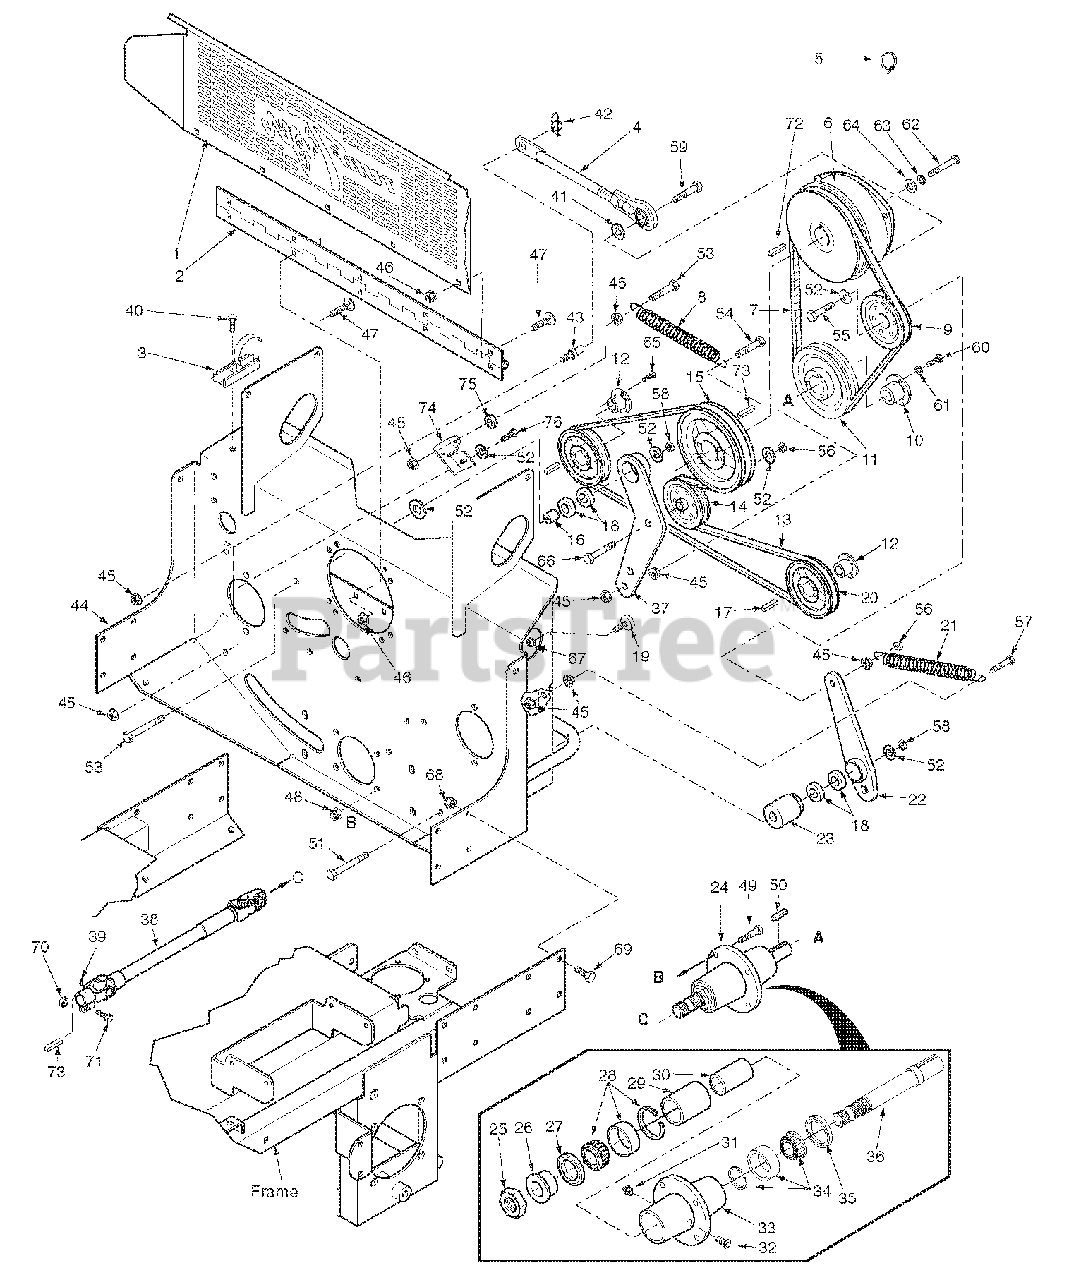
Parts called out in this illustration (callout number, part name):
1	Belt Guard, Rear
2	Hinge, Belt Guard
3	Latch, Hood
4	Rod Assembly, Clutch Anti-Rotation
5	Clamp, Cable
6	Clutch, Ogura GT-3.5
7	Belt, Deck Drive
8	Spring, Transmission Idler
9	Pulley, Idler 5" Dia.
10	Tapered Hub, 1" Bore
11	Pulley, 6.70" Tapered Bore
12	Tapered Hub, 17mm Bore
13	Belt, Pump Drive
14	Pulley, Idler 4" Dia.
15	Pulley, 5.367" Dia. - 1.125" Bore
16	Spacer, Idler Bearing
17	Key, 5.0 x 5.0 x 25mm
18	Ball Bearing
19	Bumper, Rubber
20	Pulley, 5.75" O.D.
21	Spring, PTO
22	Idler Arm Weldment, PTO Drive
23	Pivot, Idler PTO
24	Spindle Assembly, Deck Drive
25	Nut, 1.06-18 Thread
26	Spindle Bushing, Bottom
27	Seal, 2.0" O.D. x 1.625" Bore
28	Roller Bearing Tapered
29	Spacer, Outside
30	Spacer, Inside
31	Grease Fitting, 1/4-28
32	Relief Fitting
33	Spindle Housing
34	Roller Bearing Tapered
35	Seal, 2.0" O.D. x 1.5" Bore
36	Shaft, Deck Drive
37	Idler Arm Weldment, Pump Drive
38	Driveshaft (Liquid-Cooled Engine)
39	Set Screw, 3/8-16 x 3/4" Torx Socket
40	Screw, #10-32 x .56
41	Flatwasher, 3/8 (.391 x .938 x .105")
42	Pin, Rue Cotter 3/8" Dia.
43	Stud, Anti Rotation
44	Pump Mounting Plate Weld. (Liquid-Cooled)
45	Nut, Serr. Flng. 3/8-16
46	Nut, Serr. Flng. 1/4-20
47	Bolt, Carriage 1/4-20 x 1/2"
48	Nut, Elastic Stop 5/16-18 Grd. 8
49	Bolt, Hex Hd. 5/16-18 x 1-3/4" Grd. 8
50	Key, 1/4 x 1/4 x 1-1/2"
51	Bolt, Hex Hd. 3/8-16 x 4-1/2" Grd. 8 Black
52	Washer, 3/8" Hardened
53	Bolt, Hex Hd. 3/8-16 x 1-3/4" Grd. 8 Black
54	Bolt, Hex Hd. 3/8-16 x 1-1/2" Grd. 8 Black
55	Bolt, Hex Hd. 3/8-16 x 2-1/2" Grd.8
56	Nut, Center Lock 3/8-16
57	Bolt, Hex Hd. 3/8-16 x 1-1/2" Grd. 8 Black
58	Nut, Elastic Stop 3/8-16
59	Bolt, Hex Hd. 3/8-16 x 2"
60	Bolt, Hex Hd. 1/4-20 x 1-3/8"
61	Lockwasher, 1/4" Spring
62	Bolt, Hex Hd. 7/16-20 x 2-1/2" UNF
63	Lockwasher, 7/16" Spring
64	Flatwasher, 7/16 (.469 x 1.75 x .25")
65	Bolt, Hex Hd. 1/4-20 x 1" Grd. 8
66	Bolt, Hex Hd. 3/8-16 x 1-3/4"
67	Nut, Serr. Flng. 5/16-18
68	Nut, Elastic Stop 3/8-16
69	Bolt, Hex Hd. 3/8-16 x 1"
70	Nut, Center Lock 3/8-16
71	Bolt, Hex Hd. 3/8-16 x 1-3/4"
72	Key, 1/4 x 1/4 x 2-1/4"
73	Key, 1/4 x 1/4 x 1"
74	Bracket
75	Spacer
76	Bolt, Hex Hd. 3/8-16 x 1"
